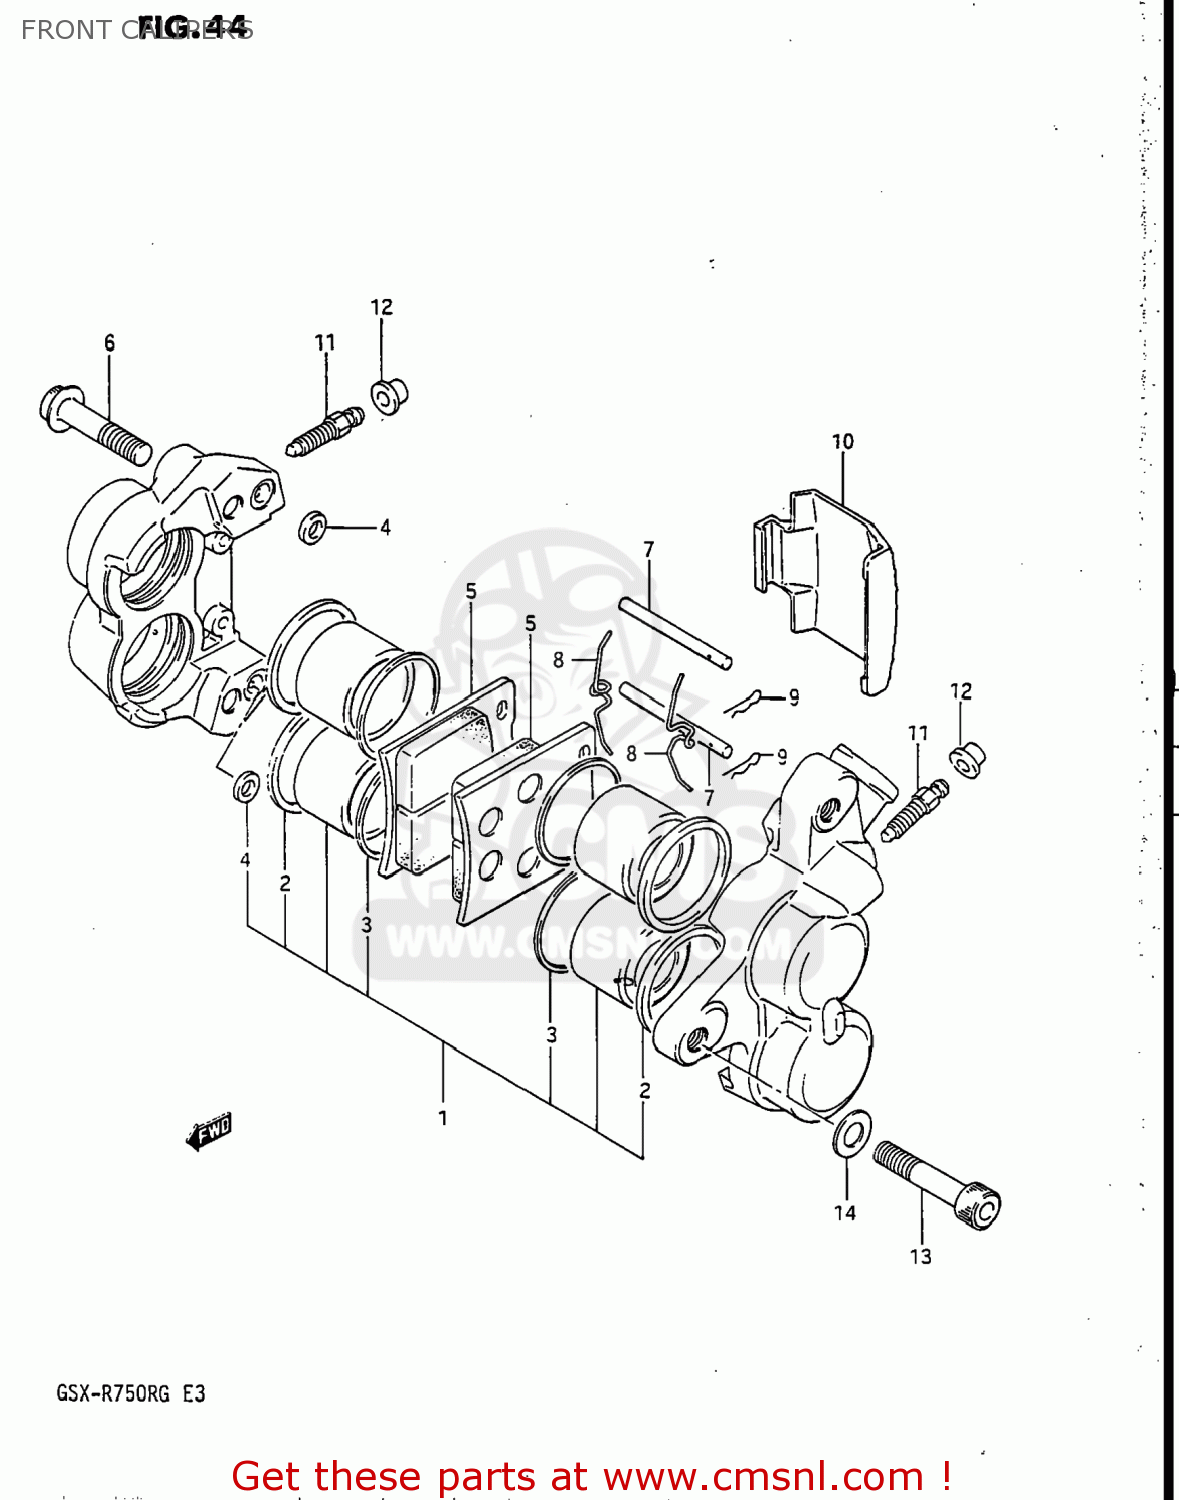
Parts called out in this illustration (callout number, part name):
1	PISTON SET
2	SEAL,PISTON
3	SEAL,WIPER
4	SEAL,JOINT
5	PAD
6	BOLT,HOUSING
7	PIN,PAD
8	SPRING
9	CLIP,PAD PIN
10	COVER,CALIPER
11	BLEEDER
12	CAP,BREATHER
13	BOLT(8X35)
14	WASHER
